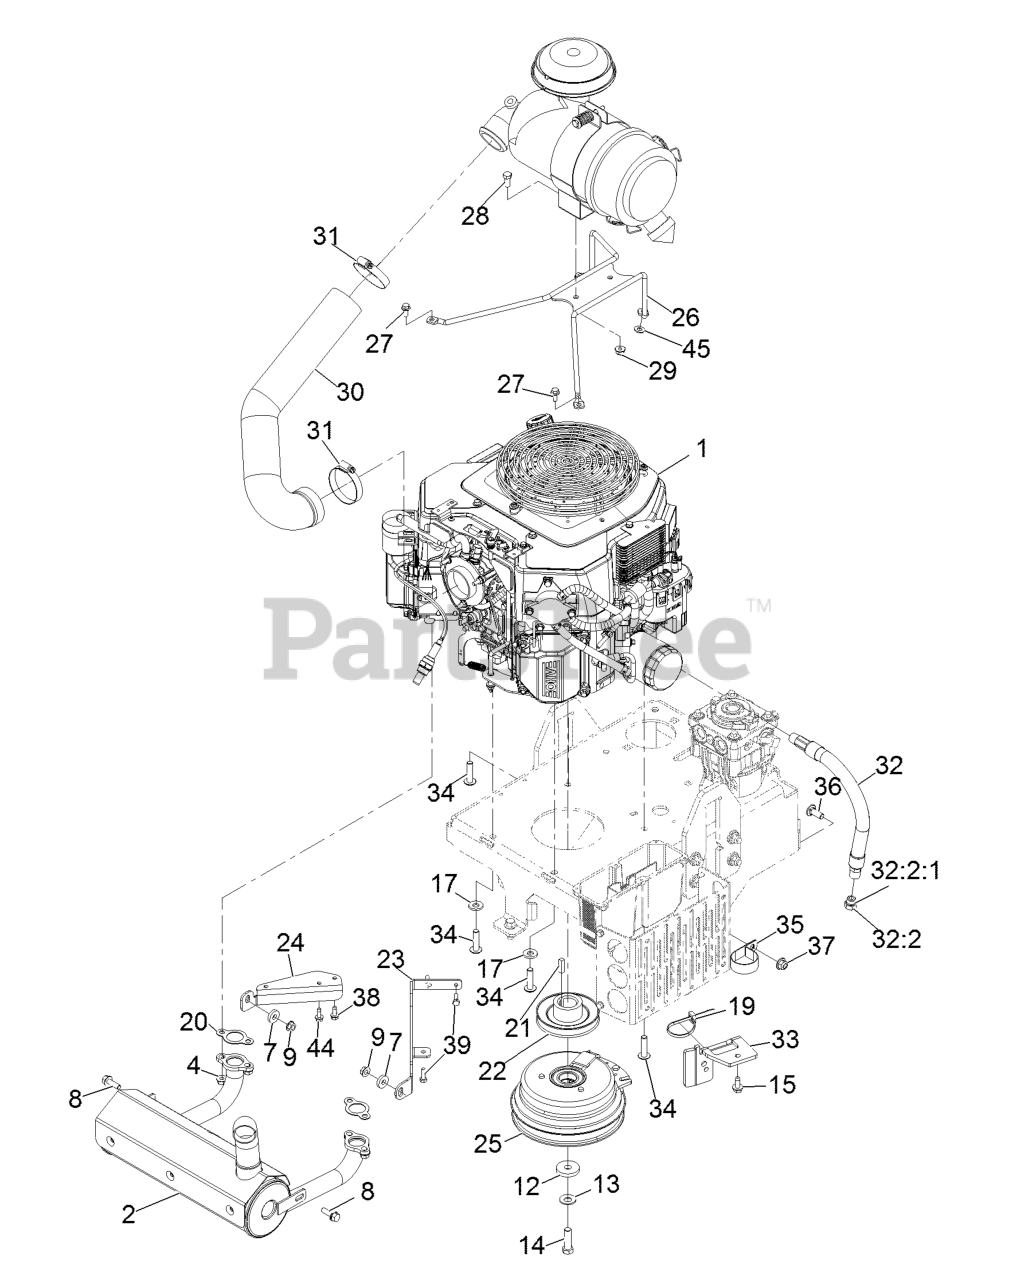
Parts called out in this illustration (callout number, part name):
1	Engine, Kohler
4	NUT-FLANGE
8	SCREW-HHF
12	WASHER
13	WASHER-SPRING
14	SCREW-HH
15	Screw-HWH 5/16-18 X 3/4 Tf
17	WASHER-BELLEVILLE
19	TIE-CABLE
20	GASKET-EXHAUST
23	MOUNT, MUFFLER-LT
24	MOUNT, MUFFLER-RT
25	CLUTCH-200 FT-LB, 1.125 B
26	MOUNT-CLEANER, AIR
27	SCREW-HHF
28	SCREW-HH
29	NUT-HF, NI
30	HOSE-INTAKE, AIR
31	CLAMP-HOSE
32	OIL DRAIN HOSE ASM
32:2	PLUG-HH
32:2:1	O-RING
33	BRACKET-ANCHOR, CLUTCH
34	SCREW-BHTF
35	CLAMP-R
36	SCREW-CARR
37	NUT-HF, NI
38	SCREW-HWHTF
39	SCREW-HH M6-1 X 20Mm W/Patch
44	SCREW-HWHTF
45	WASHER-PLAIN
